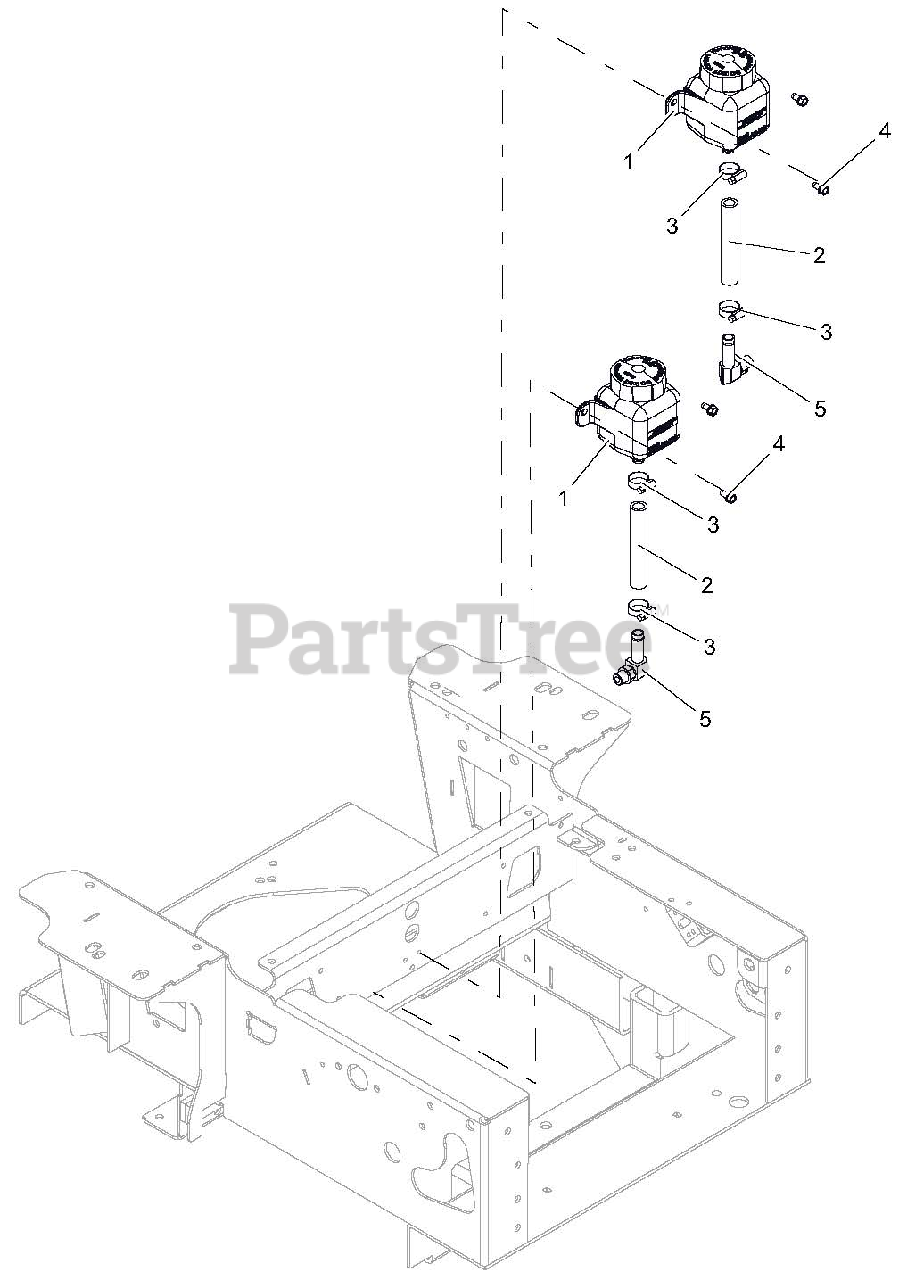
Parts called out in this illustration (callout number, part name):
1	TANK, EXPANSION ZT2800
2	HOSE, PT100 HYDRO OVERFLOW
3	CLAMP, .88 DIA HOSE
4	SCR-TAP .25-20X.50 HWH TR YWZ
5	FITTING, HYD (90 DEG)
